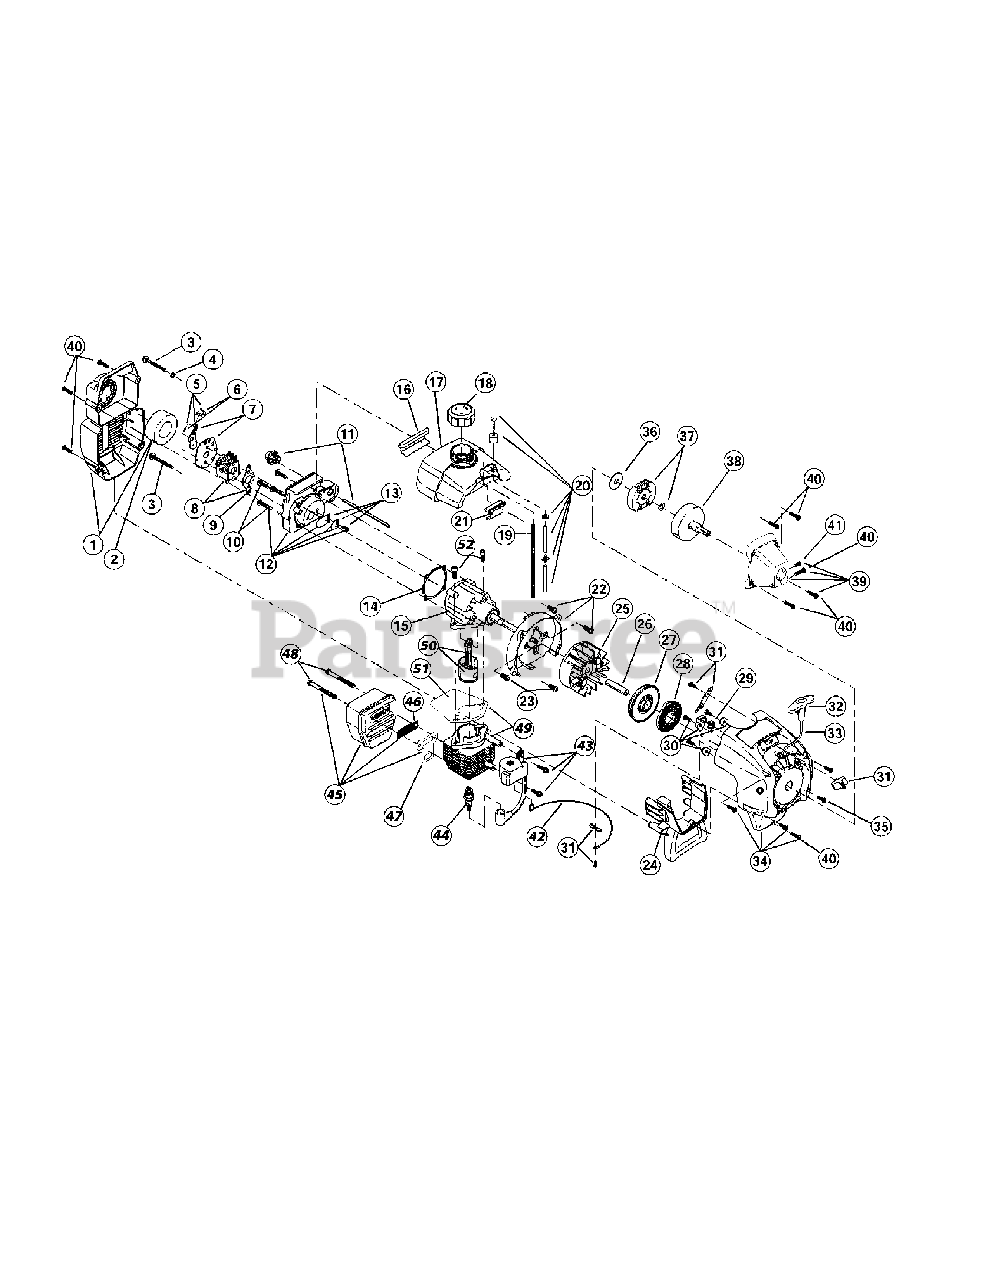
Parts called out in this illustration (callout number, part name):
1	Air Cleaner/Muffler Cover Assembly
2	Air Cleaner Filter
3	Carburetor Mounting Screw Assembly
4	Wavey Washer
5	Choke Lever Assembly
6	Choke Knob and Screw
7	Choke Lever and Plate
8	Carburetor Assembly
9	Carburetor Gasket
10	Carb Mount Screw
11	Primer and Hose Assembly
12	Carb Mount Assembly
13	Reed Assembly
14	Carburetor Mount Gasket
15	Crank Case Service Assembly
16	Rear Mounting Pad
17	Fuel Tank Assembly
18	Fuel Cap Assembly
19	Fuel Return Line
20	Fuel Line Assembly
21	Front Mounting Pad
22	Shroud Assembly
23	Shroud Screw
24	Shroud Extension and Stand
25	Flywheel Assembly
27	Recoil Pulley Assembly
28	Recoil Spring
29	Rope Guide
30	Pulley Retainer Assembly
31	Switch Assembly
32	Pull Handle
34	Starter Housing Assembly
35	Housing Screw
36	Clutch Washer
37	Clutch Rotor Assembly
38	Clutch Drum Assembly
39	Clutch Cover Assembly
40	Cover Screw
41	Anti-Rotation Screw
42	Wire Lead
43	Module Assembly
44	Spark Plug
45	Muffler Assembly
46	Spark Arrestor Screen
47	Exhaust Gasket
48	Muffler Mounting Bolt Assembly
49	Cylinder Assembly
50	Piston and Rod Assembly
51	Cylinder Gasket
52	Cylinder Bolt
